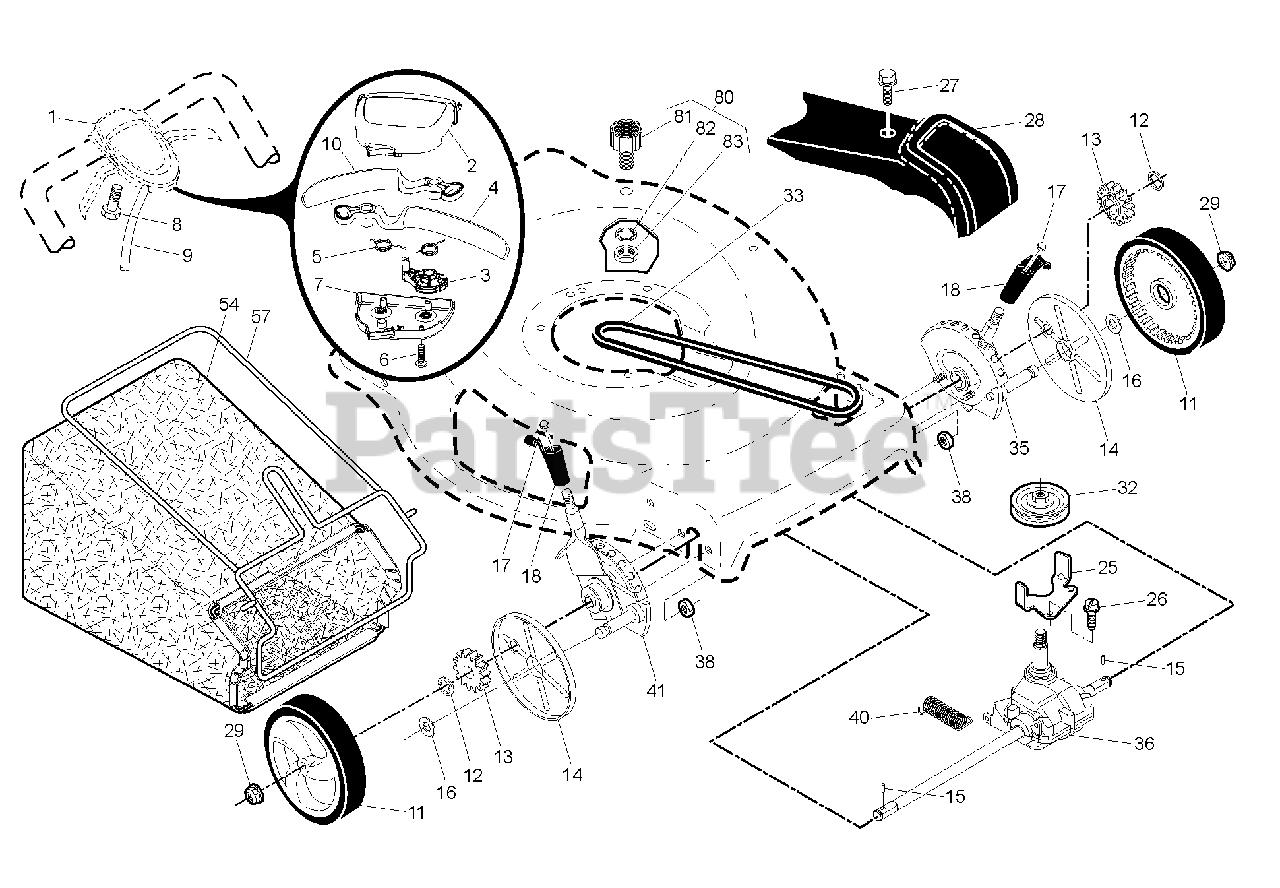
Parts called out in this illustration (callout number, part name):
3	CAM.VSC.DRIVE.CABLE
5	SPRING, DRIVE CONTROL
6	SCREW, PHILLIPS HEAD 10 X 5/8
7	COVER.DRIVE.LOWER.VSC.BLACK
12	E-RING 7/16 RE
13	PINION.14.TEETH.FGD
14	COVER.DUST.WHEEL
15	PAWL, DRIVE
16	WASHER FLUT
25	BRACKET.BELT.GUIDE.22+FGD.BZP
29	NUT.HEX.FLANGE.3/8-16.LOCKNUT
32	RP PULLEY.DRIVE.EZ
38	NUT.HEX.FLANGE.1/4
57	FRAME.GBAG.22PLUS
80	KIT.WASH-OUT.PORT
81	FITTING, HOSE, WATER WASHOUT
82	WASHER.LOCK.INTERNAL.TOOTH
83	LOCKNUT.HEX.WITH.O-RING
